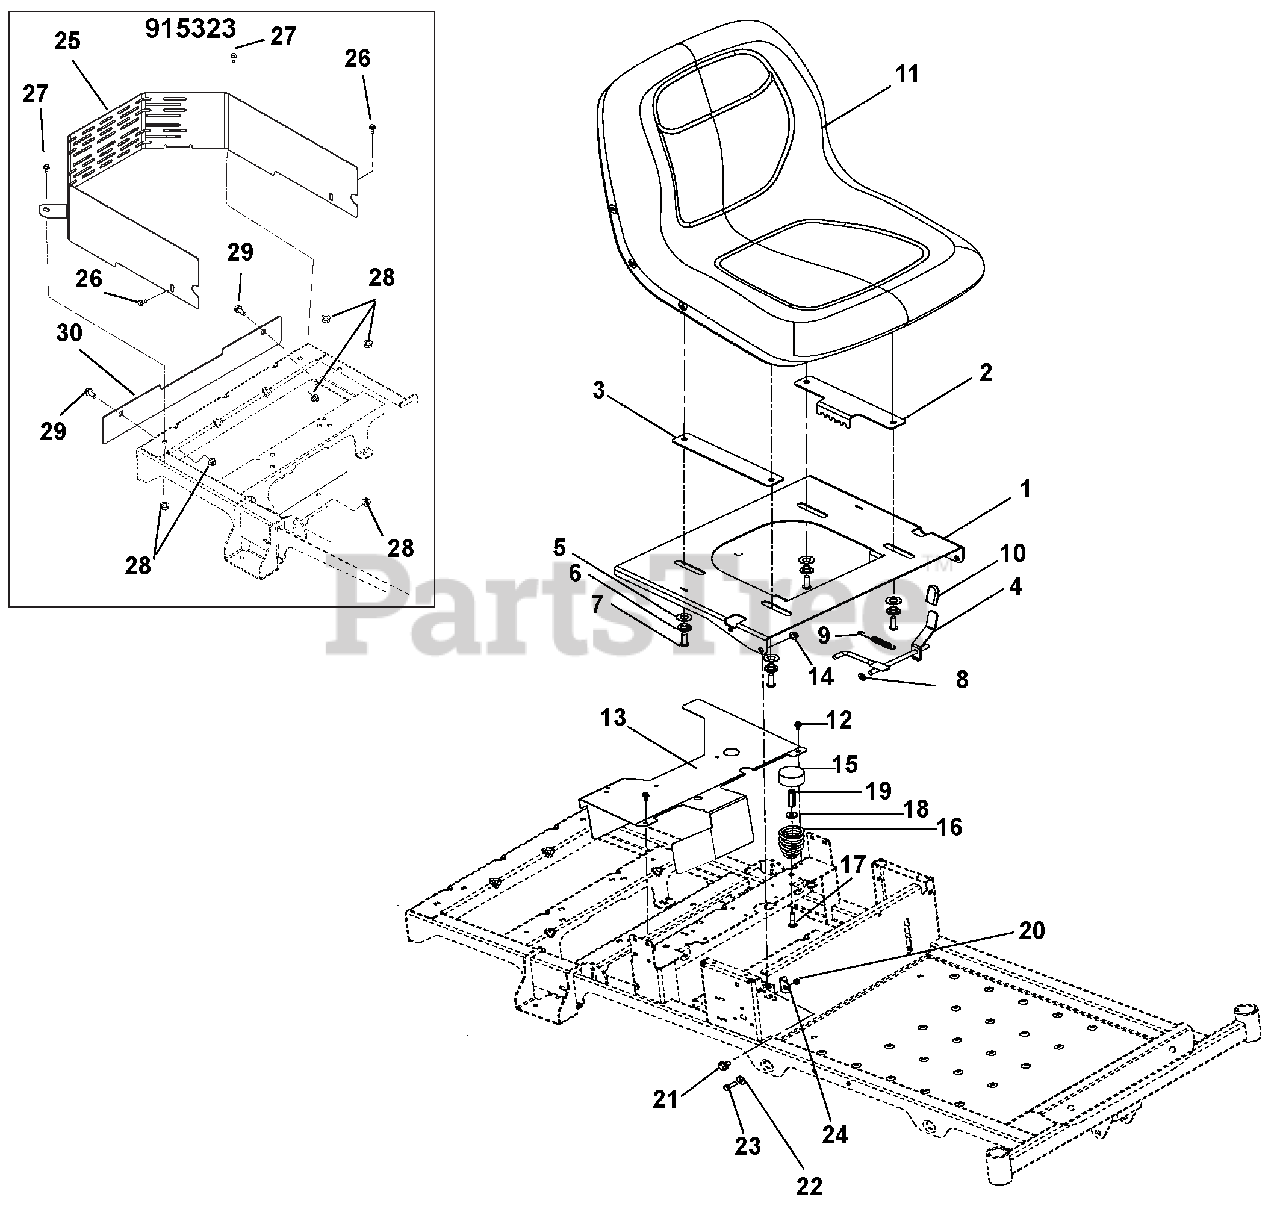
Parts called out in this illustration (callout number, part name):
1	PLATE, SEAT, ADJUSTABLE
2	PLATE, ADJUSTABLE SEAT TRACK
3	PLATE, ADJUSTABLE SEAT SLIDE
4	WLDMT, ADJUSTABLE SEAT LATCH
5	WSHR-FL-STL .505X1.00X.062YWZC
6	BSHG-FLG .32X.500X.344X.880
7	SCR-SKH .31-18X1.0 BTNHD YWZC
8	NUT-PUSH .312
9	SG-TENS .043X.44X3.31 WLD 5.8
10	GRIP, SEAT LEVER, GREY
11	SEAT, MILSCO XB180 GRAY
12	@SCR-TAP .25-20X.50 HWH TR YWZ
13	COVER, ZOOM CE FAN
14	@NUT-LK-TOP-FLG .38-16 YWZC
15	HUB CAP
16	SPRING, SEAT
17	@BLT-RDHDSQNK .31-18X1.50 G5YZ
18	WSHR-FL-STL .328X.87X.179 YWZC
19	NUT, COUPLING 5/16-18 X 1 3/4
20	@NUT-LK-NYL-FLG .31-18 YWZC
21	BOLT-SHLDR .375-16X.150
22	BSHG, FLG .325X.499X.26X.88
23	@BLT-HEX .31-18X1.00 GR5 YWZC
24	BRKT, SEAT STOP
25	WALL, CE REACH-IN (ZOOM)
26	@BLT-HEX .38-16X.75 GR5 YWZC
27	@BLT-HEX .38-16X1.00 GR5 YWZC
28	NUT-LK-CTR-FLG .38-16 YWZC
29	@BLT-RDHDSQNK .38-16X.75 G5YZ
30	FLANGE, ZOOM MUFFLER (CE)
